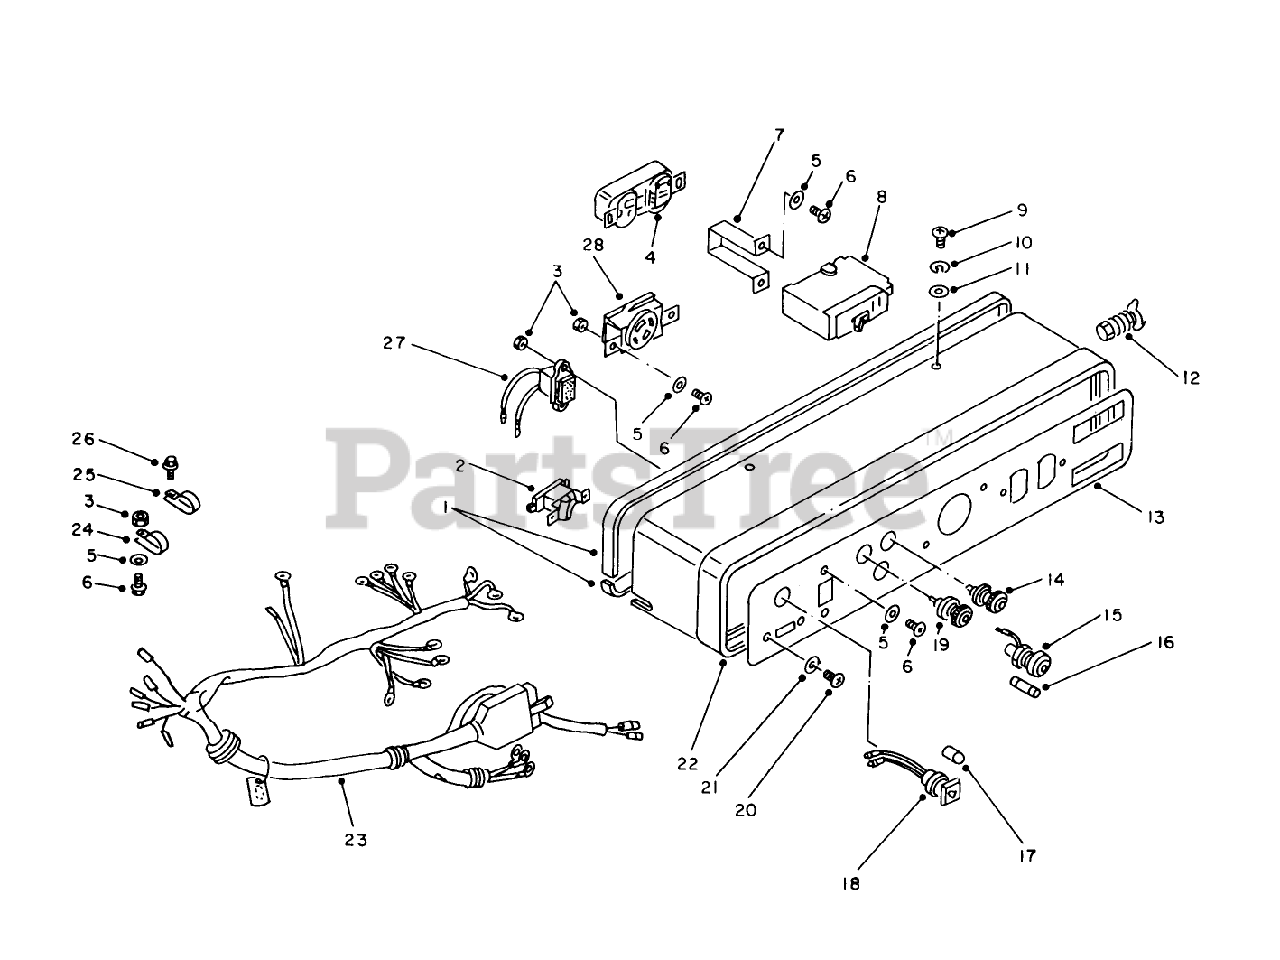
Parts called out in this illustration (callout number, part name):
2	Switch
4	Receptacle
5	Washer
6	Screw
7	Holder
8	Circuit Breaker
9	SCREW
10	Washer
11	WASHER
12	GROUND TERMINAL
13	Plate
14	Terminal
15	Fuse Holder (Incl. Ref. #16)
18	Lamp (Incl. Ref. #19)
19	TERMINAL (-)
20	SCREW
21	Washer
22	Control Panel
23	Wire Harness
24	Clamp
25	Clamp
26	SCREW-HHF
27	Hertz Meter
28	Receptacle
